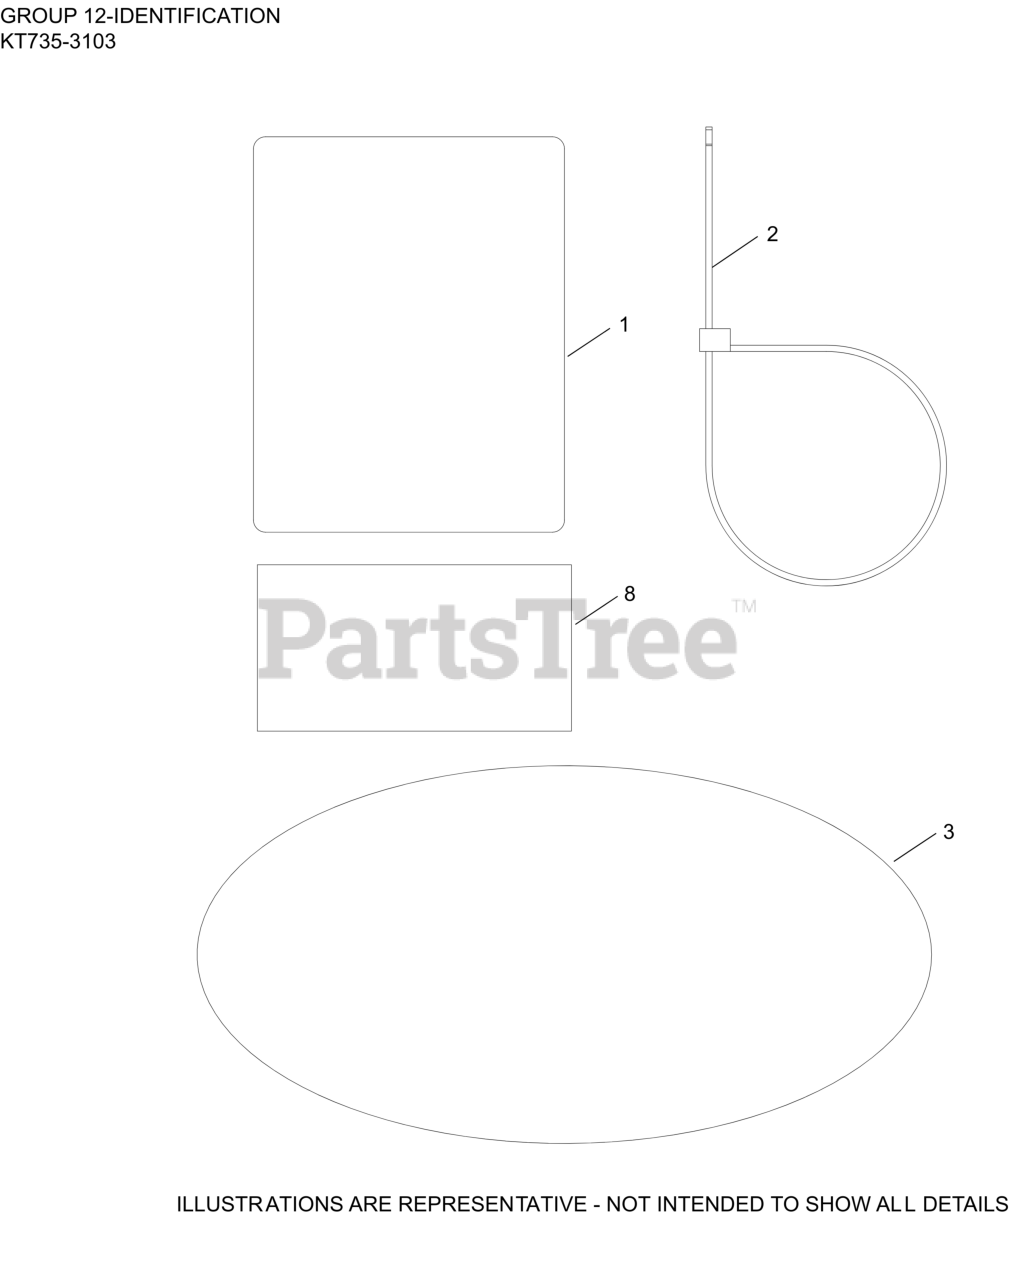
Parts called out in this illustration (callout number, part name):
1	LABEL, CLEAR LAMINATION
3	LABEL, 7000 SERIES KT735 (24 HP)
8	DECAL, USA
